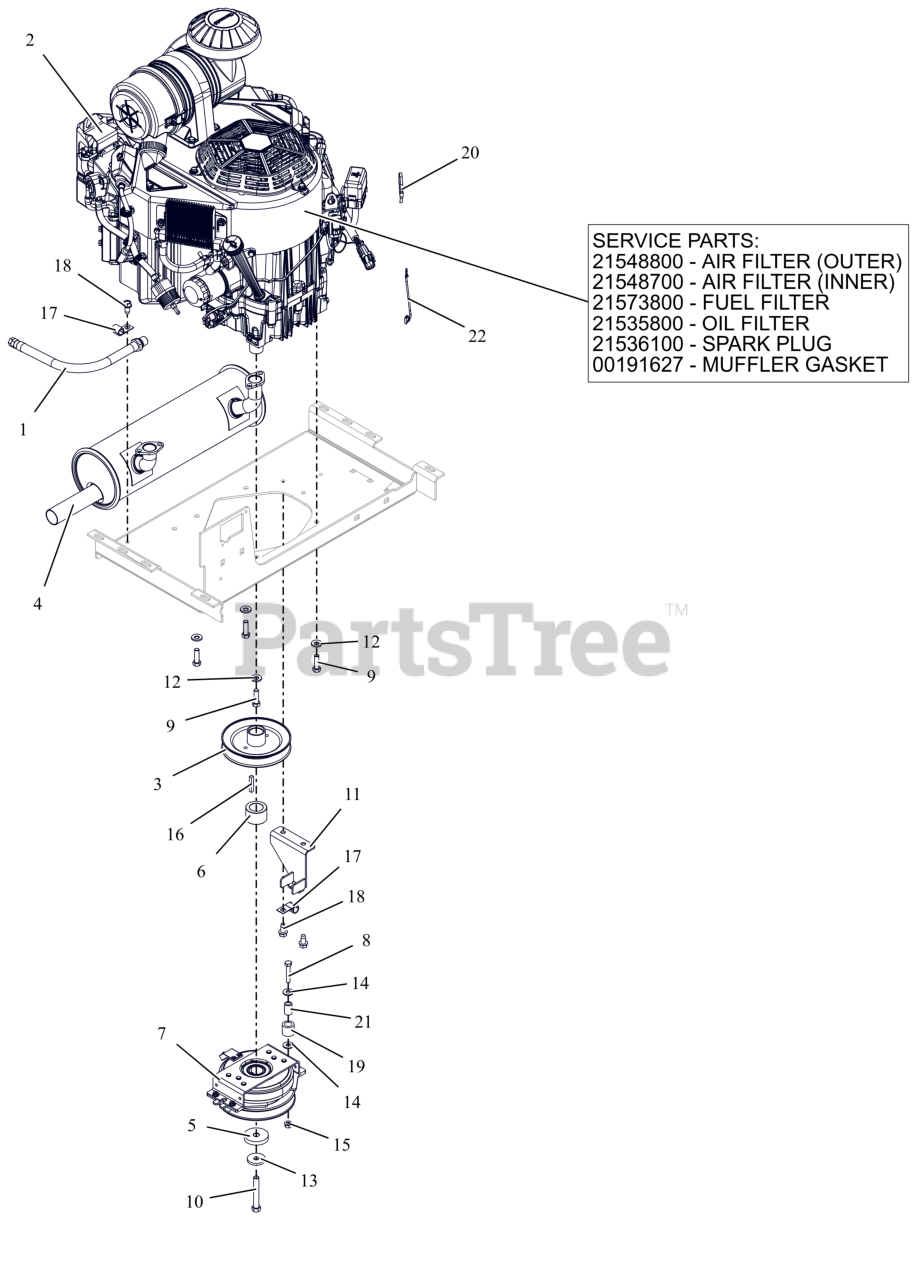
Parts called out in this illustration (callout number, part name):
1	HOSE, OIL DRAIN
2	ENGINE, KAWASAKI - FX 850 EFI W/VOLT REG
2	FILTER, OUTER
2	FILTER, INNER - KAW
2	FUEL FILTER
2	FILTER,OIL - KAW
2	PLUG, SPARK
2	GASKET, MUFFLER S/O
3	WLDMT, TRANSAXLE DRIVE PULLEY
4	MUFFLER, KAWASAKI FX850
5	SPACER, .474/.459X2.00X.350
6	SPCR, 1.125 x 1.750 x 1.147
7	CLUTCH- OGURA GT2.75-DC03(D)
8	BLT, HEX .31-18X1.75 G5 ZCC
9	BLT, HEX .38-16X1.25 G5 ZCC NT
10	BLT, HEX 0.4375-20X3 G8 ZCC NT
11	BRKT- CLUTCH STOP - BLACK
12	WASHER, 3/8" SPRING DISC
13	WASHER, 7/16" SPRING DISK
14	WSHR,FLT .375X.875X.083 ZCC
15	NUT,LK-CTR-FLG .31-18 GF ZCC
16	KEY-SQ .25 X 1.50 X .25 SAE
18	SCR,TAP .375-16X.75 HWH TR ZCC
19	BUMPER,RUBBER .62X1.0X.88 LG
20	CABLE TIE LG 5-1/2
21	BUSH.,S.391X.622X.950 ST
22	LEAD - STARTER SOLENOID
